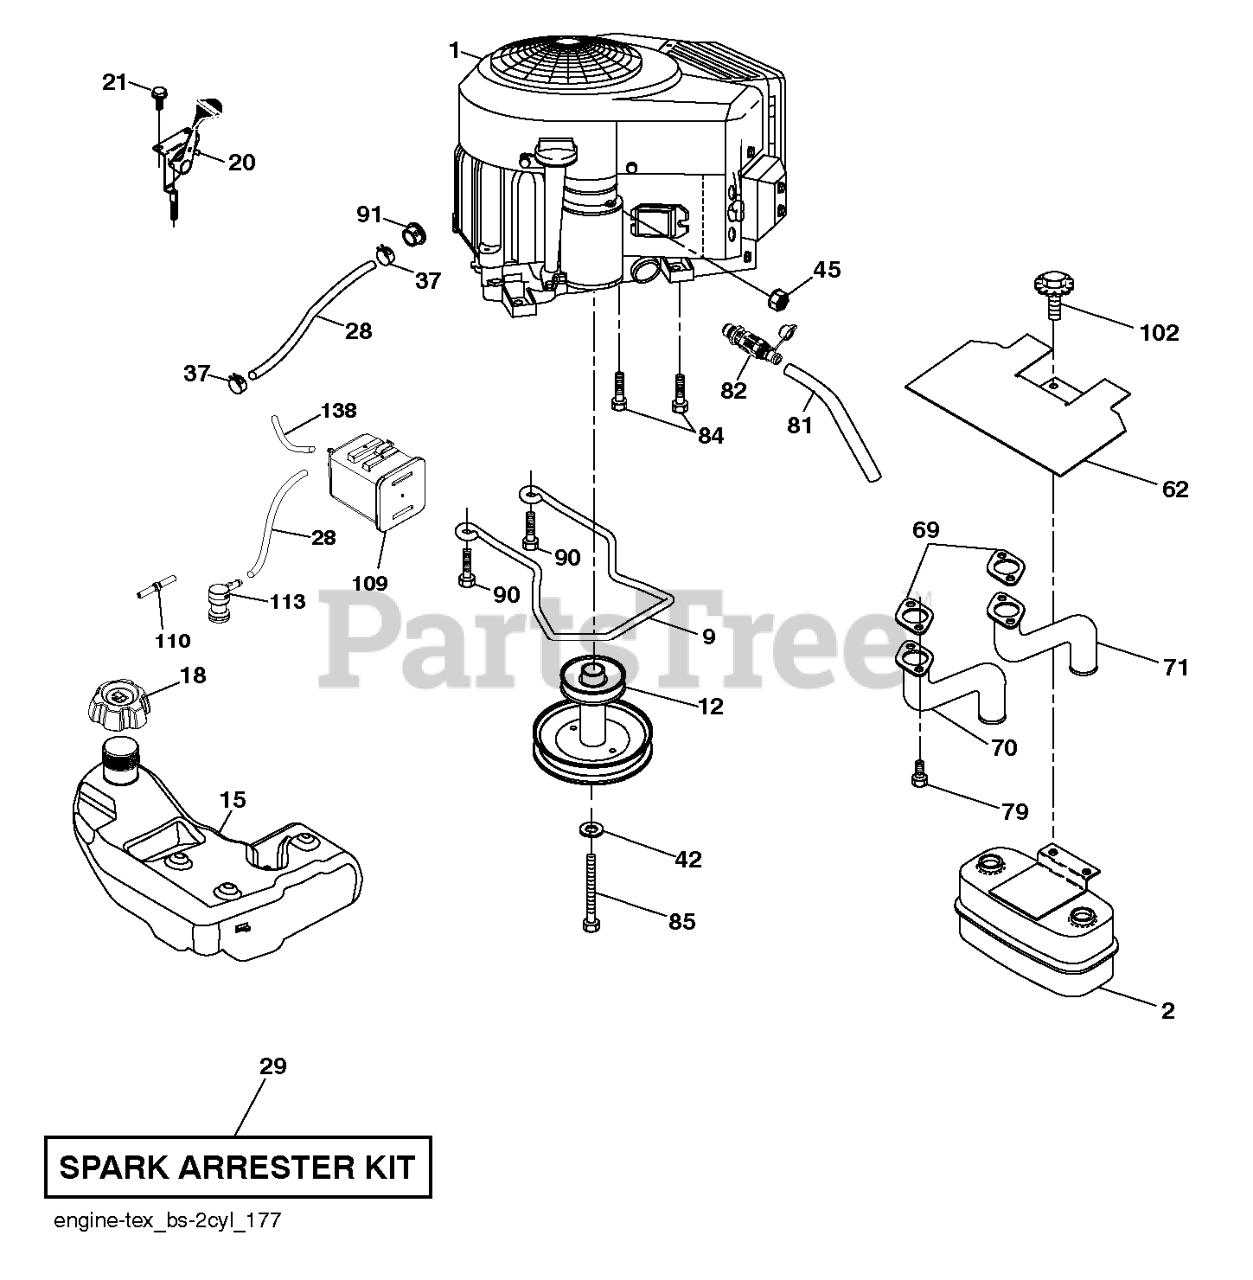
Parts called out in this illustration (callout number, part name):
2	MUFFLER.ASM.TWIN.MNTG.BRACKET
12	PULLEY.ENGINE
15	FUEL TANKS
20	CONTROL.TH/CK.COBRA.B&S.TWN.BK
28	LINE.FUEL.64"REAR.EMIS
29	KIT.SPARK ARRESTOR 794945 B&S
37	HOSE CLAMP
62	SHIELD.HEAT.MUFFLER
69	GASKET.MUFFLER
70	EXHAUST.TUBE.LH.BS/TWIN
71	EXHAUST.TUBE.RH.B&S.TWIN.INTEK
81	TUBE, DRAIN OIL ASM.
82	VALUE.OIL.DRAIN
84	SCREW.3/8-16
85	BOLT.HEX.7/16-20X4.GR5.1.5BLUE
90	SCREW 3/8-16X1
91	BUSHING.1.375OD
102	SCREW
109	CANNISTER, CARBON
110	VALVE.ASM.ANTI-SLOSH
113	VALVE.SLANT.CARTRDG.90 DEG.TEX
138	TUBE.PURGE.FUEL.1875
